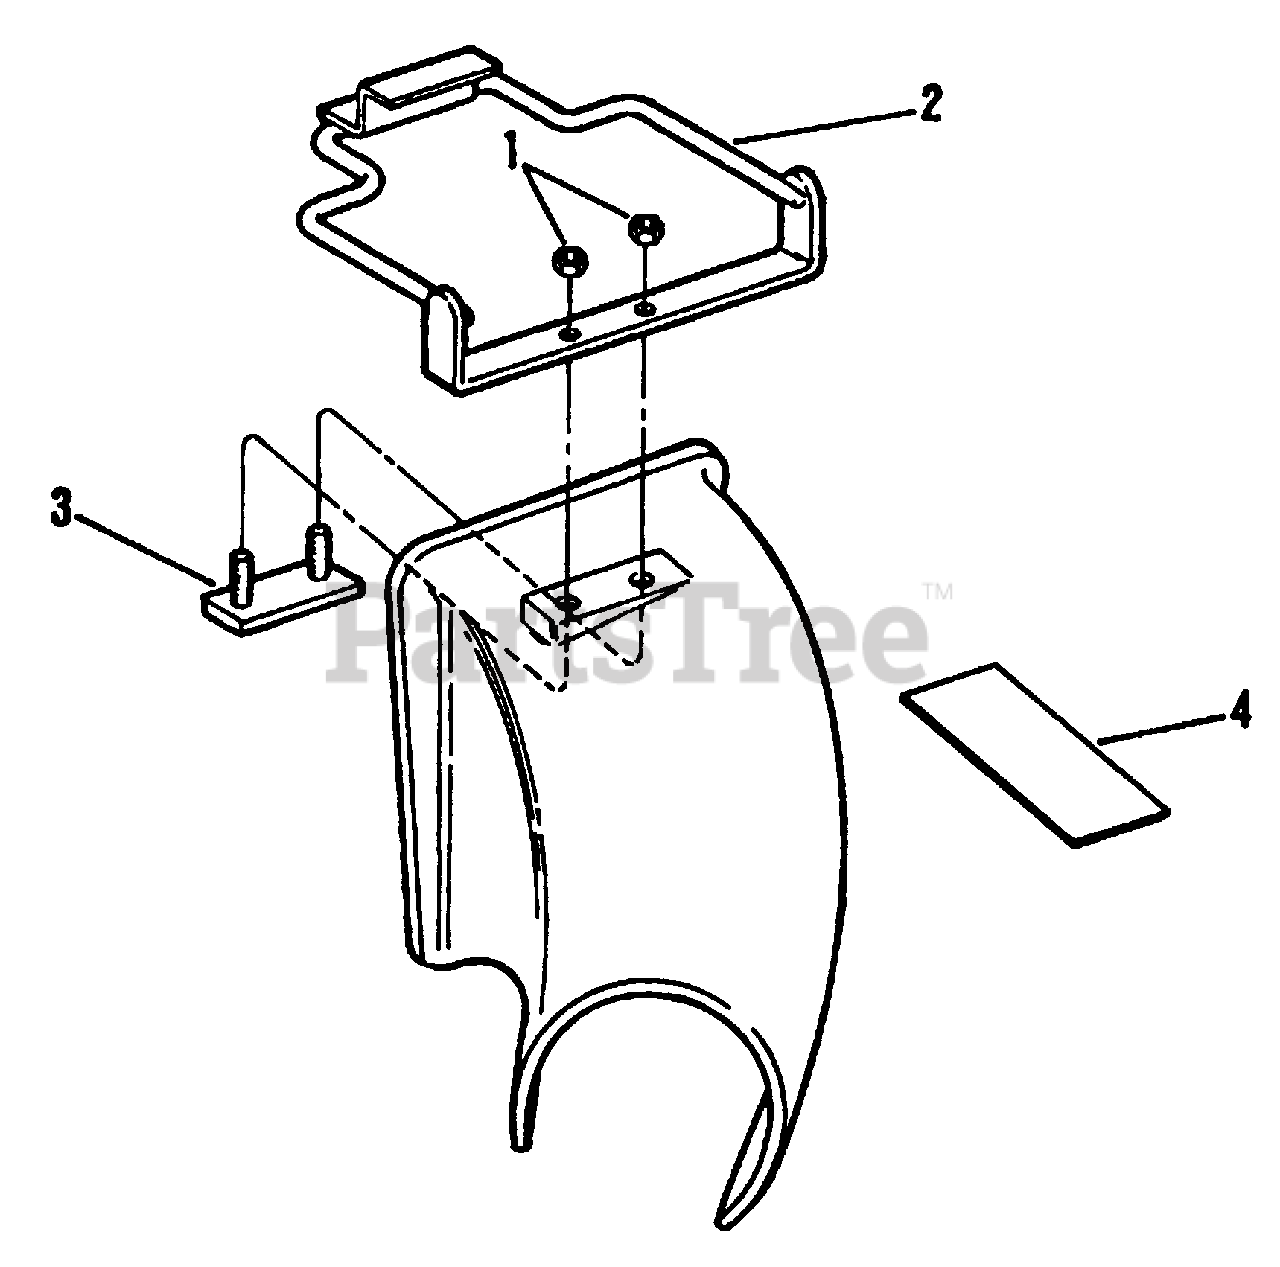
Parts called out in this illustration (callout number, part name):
1	Locknut
2	Latch Bar
3	Back-Up Plate
